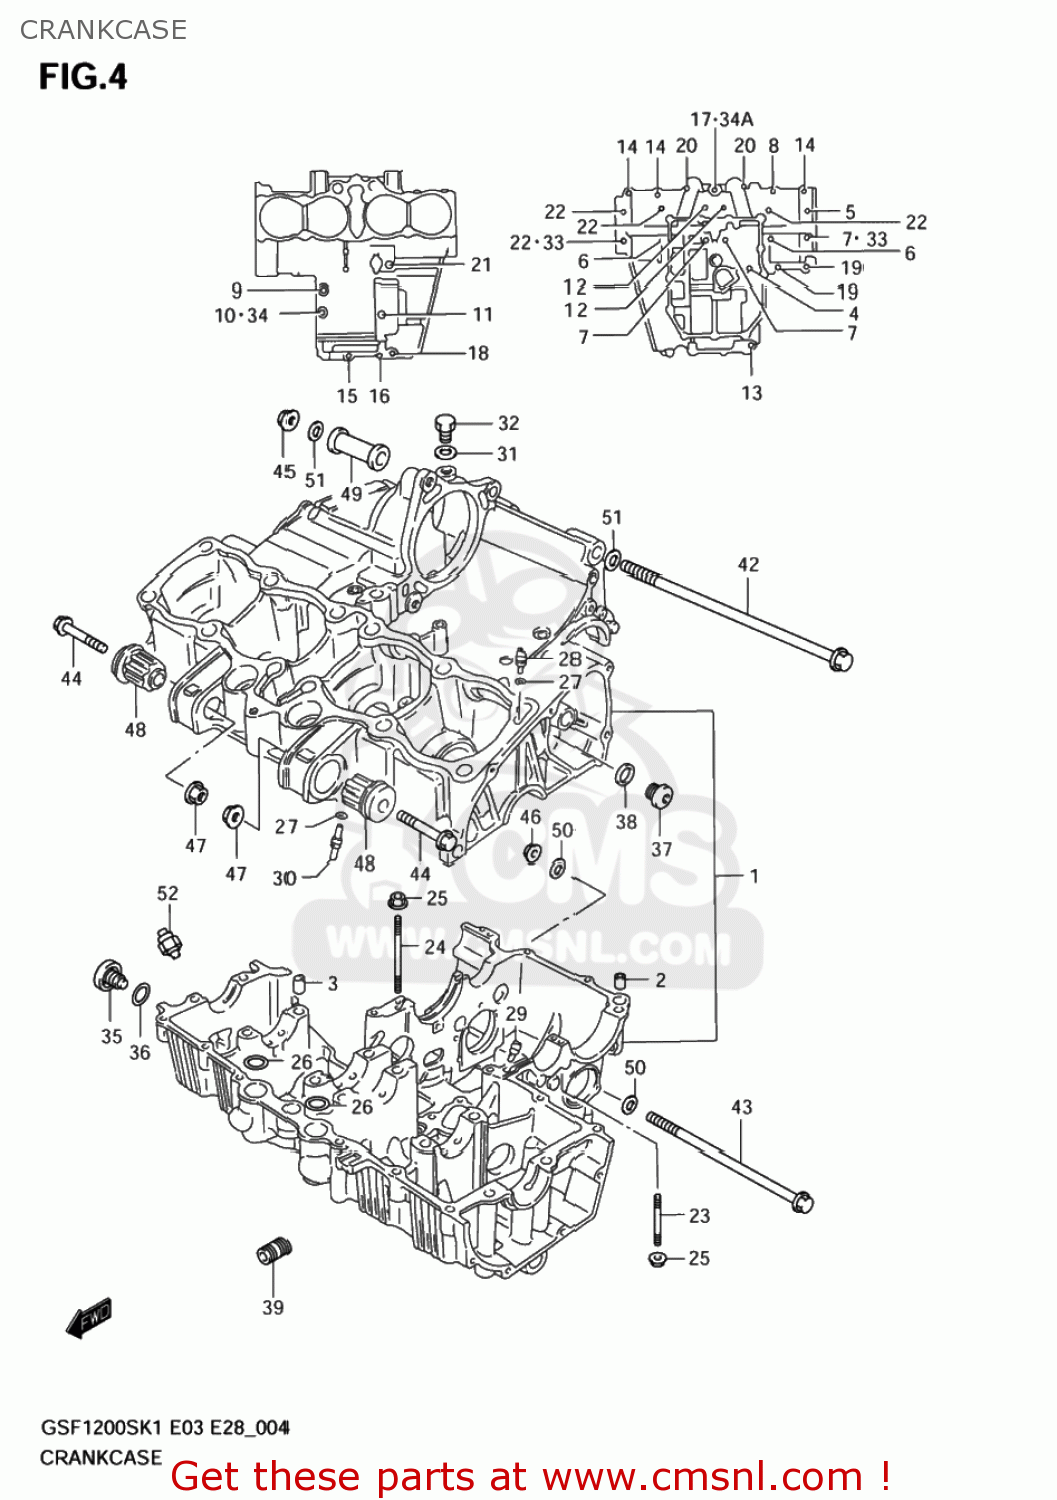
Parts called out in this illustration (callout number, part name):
1	CRANKCASE SET
2	PIN(10.4X13X22)
3	PIN(8.4X11X20)
4	BOLT(6X105)
5	BOLT(8X105)
6	BOLT(8X125)
7	BOLT(8X115)
8	BOLT
9	BOLT
10	BOLT
11	BOLT
12	BOLT
13	BOLT
14	BOLT
15	BOLT
16	BOLT
17	BOLT
18	BOLT
19	BOLT, HYDRAULIC UNIT NO.2
20	BOLT
21	BOLT
22	BOLT(8X95)
23	STUD BOLT
24	STUD BOLT
25	NUT
26	O RING(D:2.5,ID:21)
27	O RING(D:1.2,ID:4)
28	JET,AIR
29	JET
30	JET(13)
31	GASKET(12.1X16.2X3.7) (NAS)
32	PLUG(12X9)
33	GASKET(8.5X17X2.3) (NAS)
34	GASKET(6.2X13X1.2) (NAS)
34A	GASKET(5.8X13X1.2) (NAS)
35	PLUG
36	O RING(D:2.4,ID:16.8)
37	PLUG
38	GASKET(13.8X18.8X4.8) (NAS)
39	UNION,OIL STAND
40	BEARING,CRANK THRUST(GREEN)
41	BEARING,CRANK THRUST(RED)
42	BOLT(10X180)
43	BOLT(12X140)
44	BOLT(10X55)
45	NUT
46	NUT 12MM
47	NUT
48	BUSH,ENGINE MOUNTING
49	SPACER,ENGINE MOUNT(L27)
50	WASHER
51	WASHER
52	SWITCH ASSY,OIL PRESSURE
